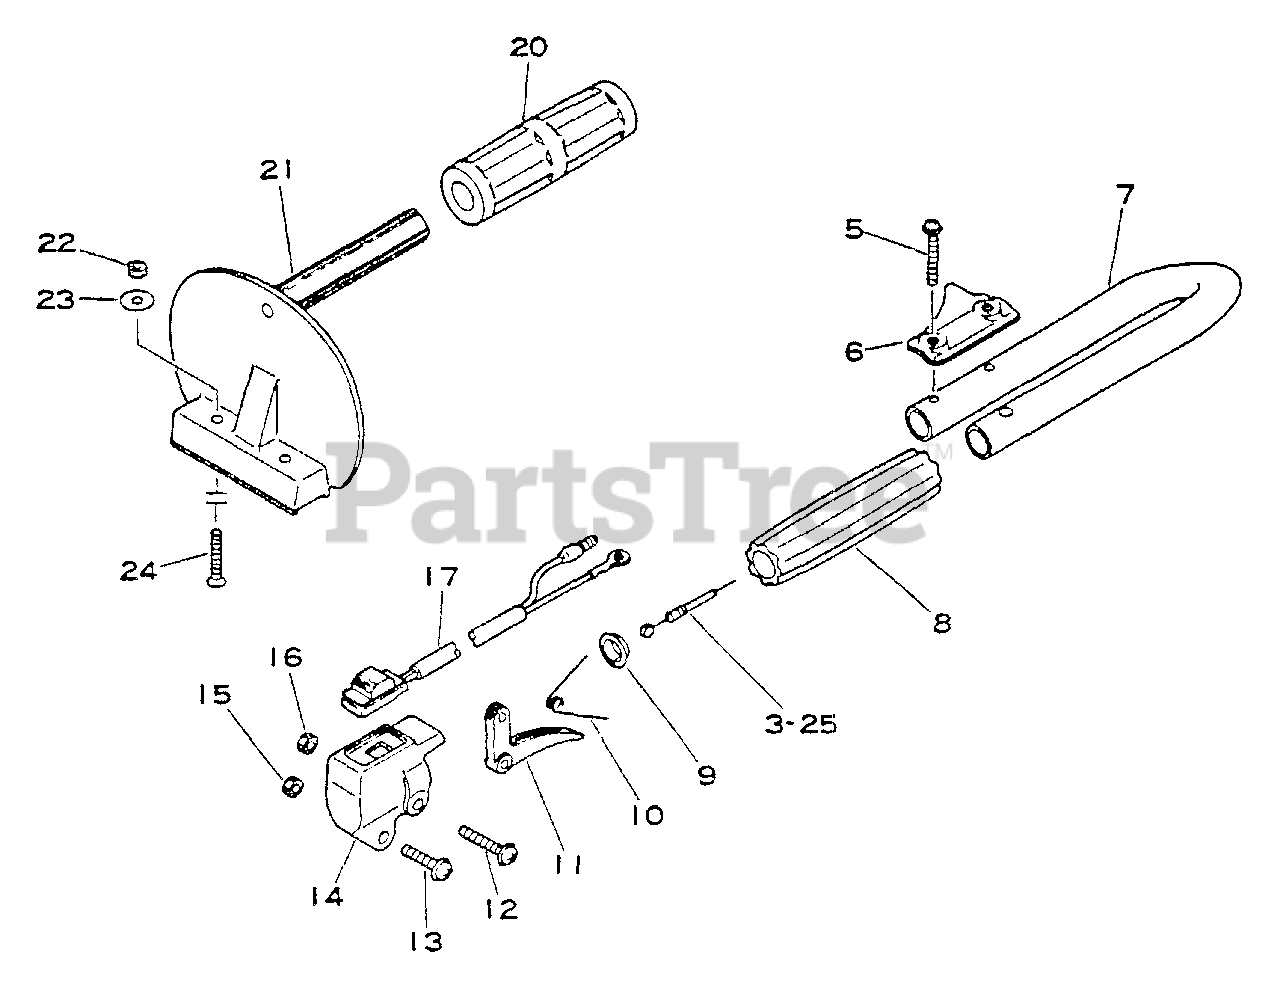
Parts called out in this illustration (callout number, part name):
5	SCREW 5×35
6	BRACKET, HANDLE
7	HANDLE - REAR
11	TRIGGER, THROTTLE
13	SCREW 5×28
14	BRACKET, THROTTLE
15	NUT M5
16	NUT, LOCK M5
21	HANDLE, FRONT
22	NUT, LOCK M5
23	WASHER 5.5×18×1
24	SCREW 5×30
25	CABLE, THROTTLE
